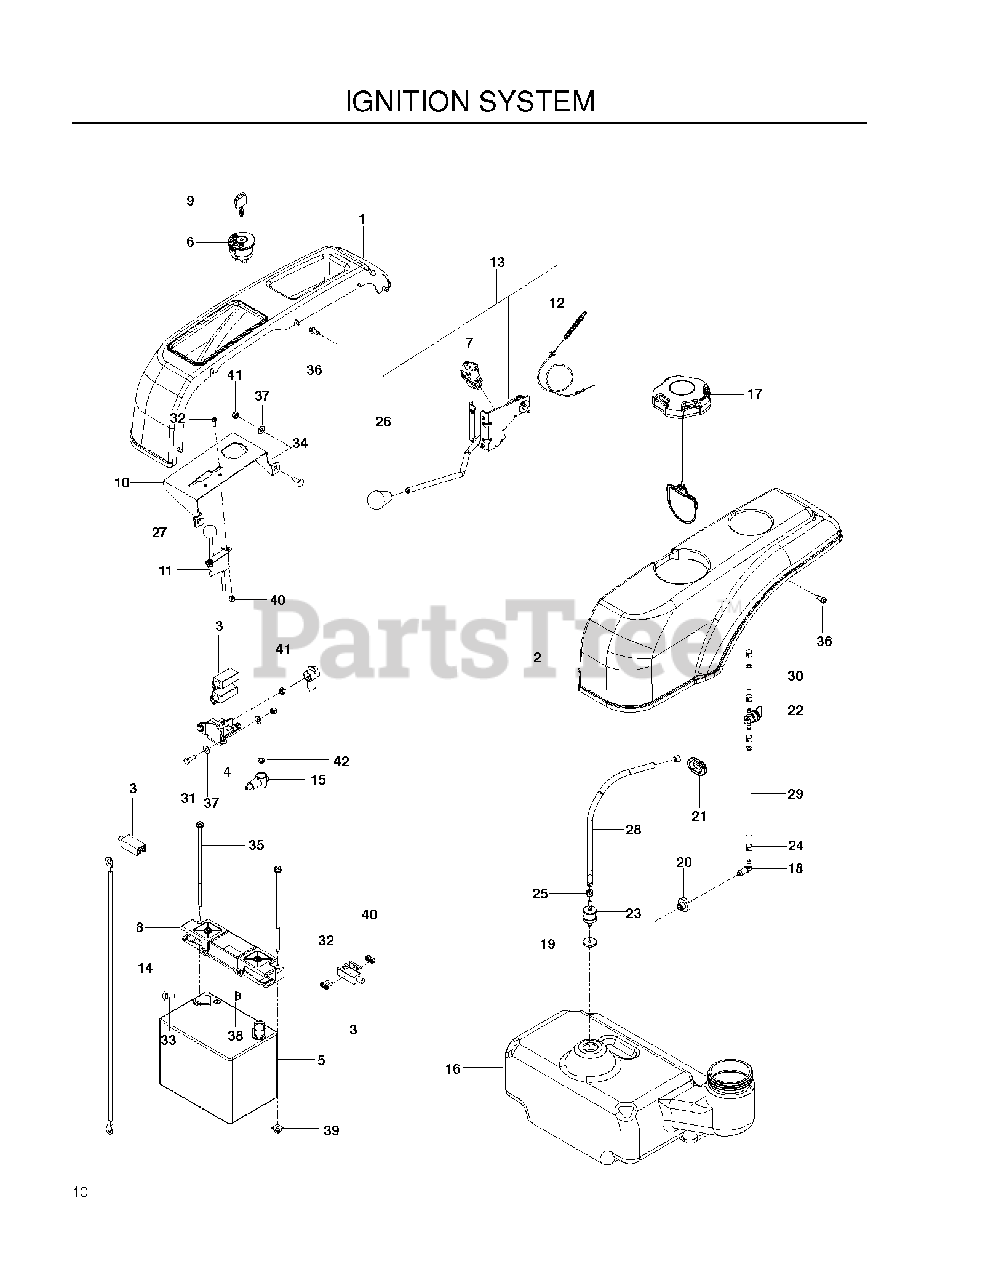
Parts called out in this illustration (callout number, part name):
1	FENDER, RZ 30/38 RT
2	FENDER, RZ 30/38 LT
3	SWITCH, INTERLOCK
5	BATTERY, 12 V 330 AMP
6	RP IGNITION SWITCH
7	SWITCH INTERLOOK PUSH-IN
8	BATTERY HOLD DOWN
9	TAPBOLT, 3/8C X 3
10	MOUNT, CONTROLS, BLK
11	CABLE, THROTTLE
12	CABLE.CLUTCH.38".SERVICE
13	ASM, CLUTCH ENGAGE W/CABLE
14	BATTERY CABLE, NEGATIVE
15	TERMINAL COVER-SM
16	TANK, FUEL EPA
17	CAP, FUEL
18	STEM, FUEL TANK
19	GROMMET, CHECK VALVE
20	RUBBER GROMMET
21	RUBBER GROMMET
22	FUEL VALVE
23	VALVE.FUEL.CHECK
24	HOSE CLAMP
25	CLAMP, HOSE
26	KNOB - SHIFT
27	KNOB.ROUND.BALL.BLACK
28	HOSE, FUEL, 3/16" X 20"
29	HOSE 1/4 X 8
30	HOSE 1/4 X 2"
31	HCS 1/4C X 3/4 HCS
32	SCREW #10-24 X 5/8
33	BOLT 5/16C X 3/4" CARRIAGE
34	RHSNB 1/4C X 3/4
35	Bolt, 1/4-20 X 7.5
36	SCREW 1/4 X 5/8
37	WASHER 1/4 SAE
38	5/16-18 NYLOC FLANGE NUT
39	PUSH NUT-NYLON
40	NUT 10-24 NYLOC
41	RP_NUT 1/4-20 NYLOC
42	JAM NUT 1/4C (2 2 PW01)
